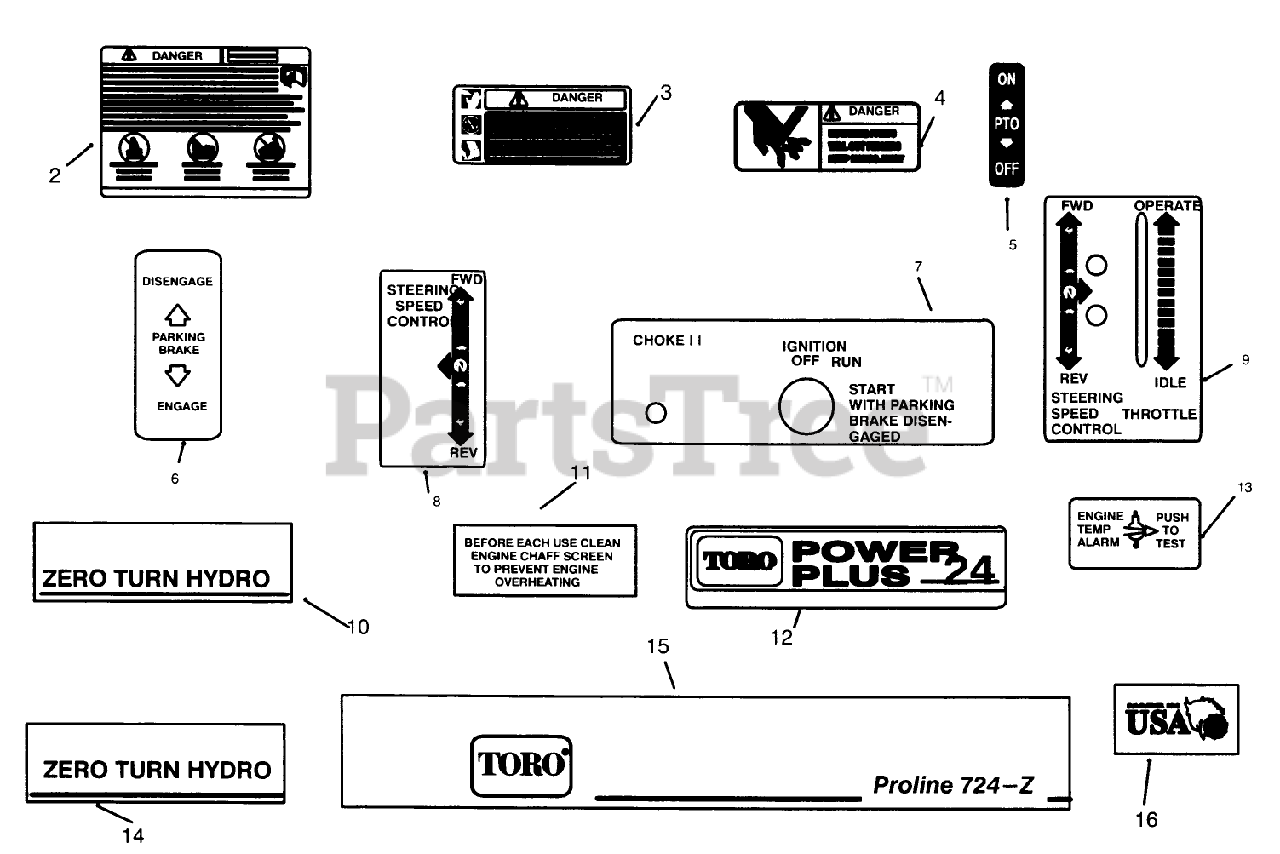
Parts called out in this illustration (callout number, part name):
2	DECAL-DANGER
3	DECAL-DANGER
4	DECAL - DANGER
5	DECAL-PTO
6	DECAL-PARKING BRAKE
7	DECAL-CHOKE/IGNITION
8	DECAL-STRG SPEED CNT
9	DECAL THROTTLE
10	DECAL-ZERO TURN R.H.
11	DECAL-ENGINE SCREEN
12	DECAL-PWR PLUS 24 PL
13	DECAL-TEMP ALARM
14	DECAL-ZERO TURN L.H.
15	DECAL-TORO 724-Z
16	DECAL - USA
